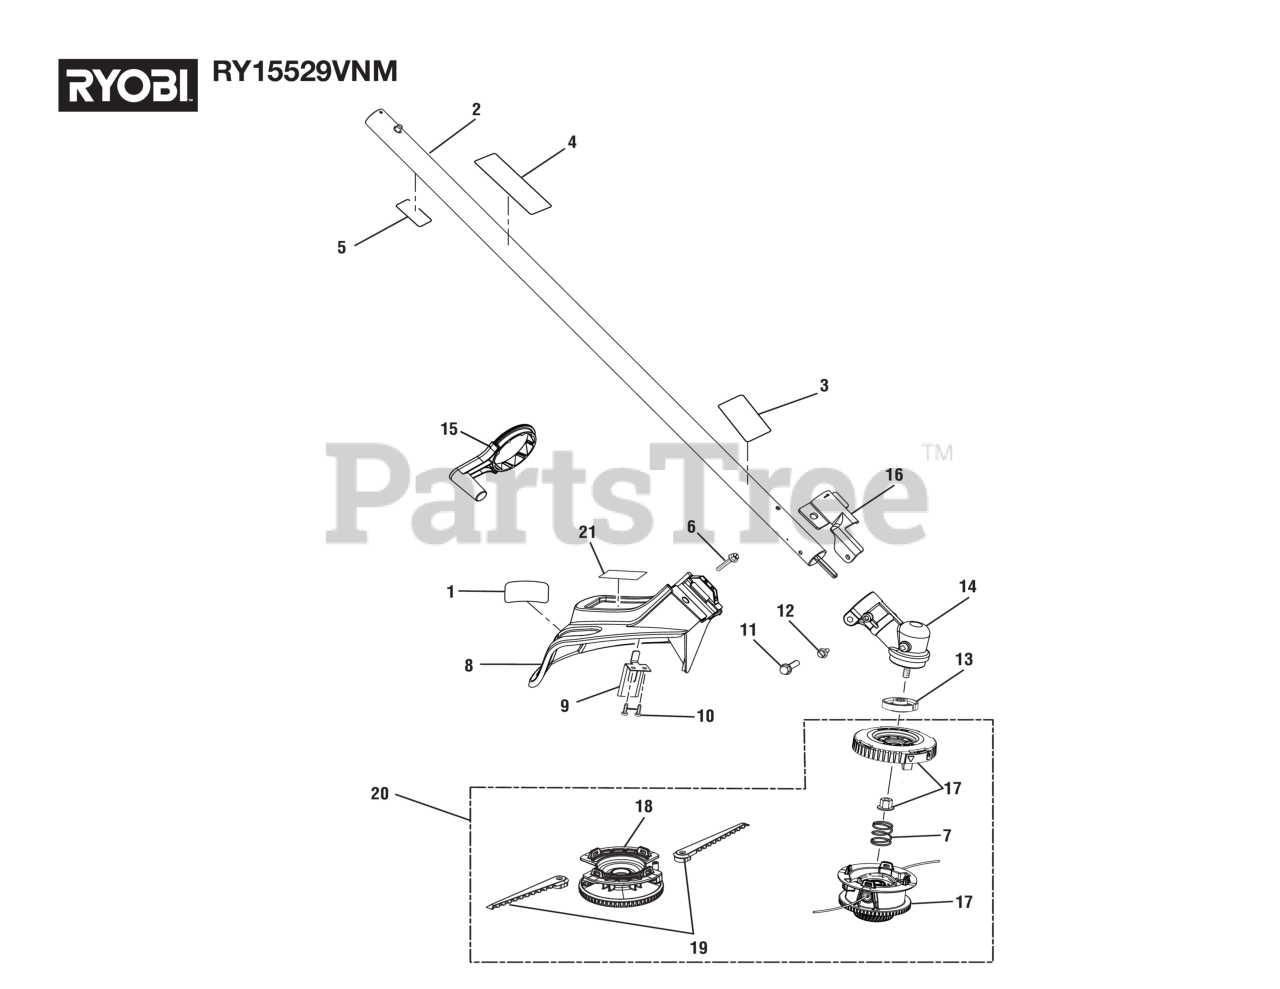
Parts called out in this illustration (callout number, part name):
1	Max. Run Time/Performance Label
2	Straight Shaft Assembly (Inc. Key Nos. 3-5)
3	Icon Warning Label
4	Carbon Fiber Label
5	Data Label
6	SCREW (#1/4-20 X 1-1/4 in. HEX WASHER HD.)
7	Compression Spring
8	Grass Deflector Assembly
9	Line Cut-off Blade
11	Screw (1/4-20 x 1-1/4 in., Hex Washer Hd. S.T.)
12	Screw w/Washer (10-24 x 5/8 in., Hex Hd. T.F.)
13	FLANGED WASHER
14	Gear Head Assembly
15	Crank Handle
16	GRASS DEFLECTOR CLAMP
17	Bump Feed Trimmer Head Assembly (Inc. Key No. 21)
18	Fixed Line and Blade Housing Assembly
19	Flail Blade
20	Stringhead Reel Assembly
21	Guard Logo Label
